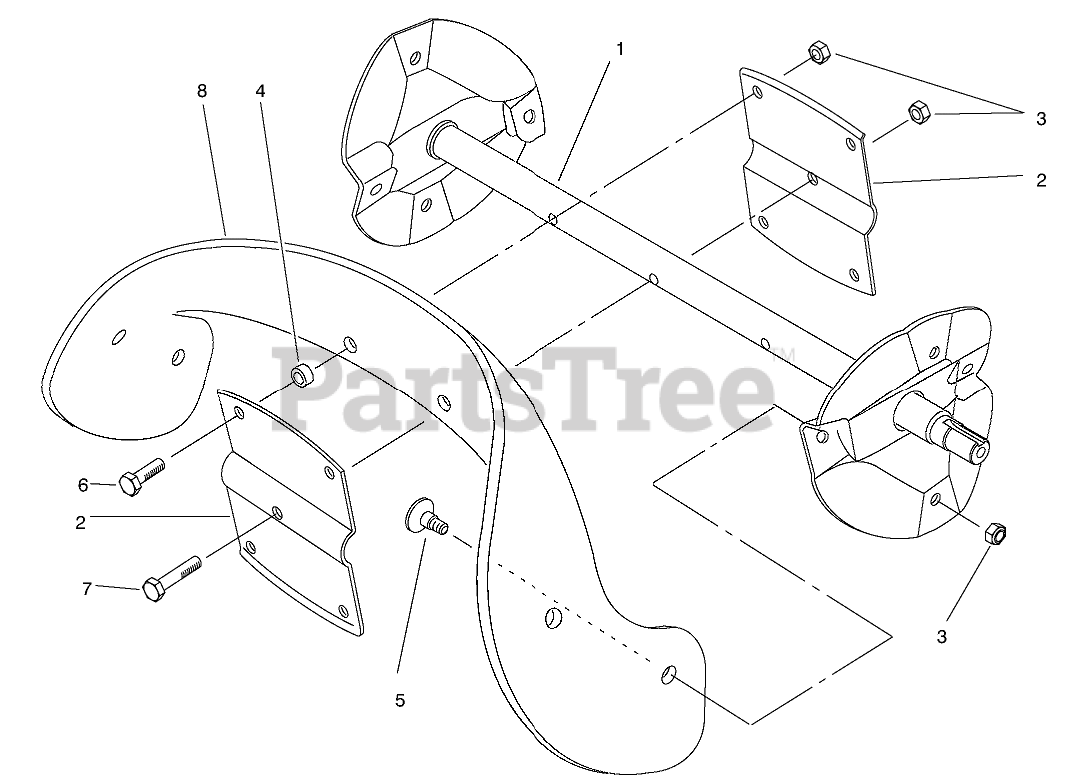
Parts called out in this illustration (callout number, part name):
1	Wa-Rotor
2	Rotor
3	NUT-LOCK, NI
4	SPACER-BLADE, ROTOR
5	SCREW
6	SCREW-HH
7	SCREW-HH
8	Blade-Rotor
